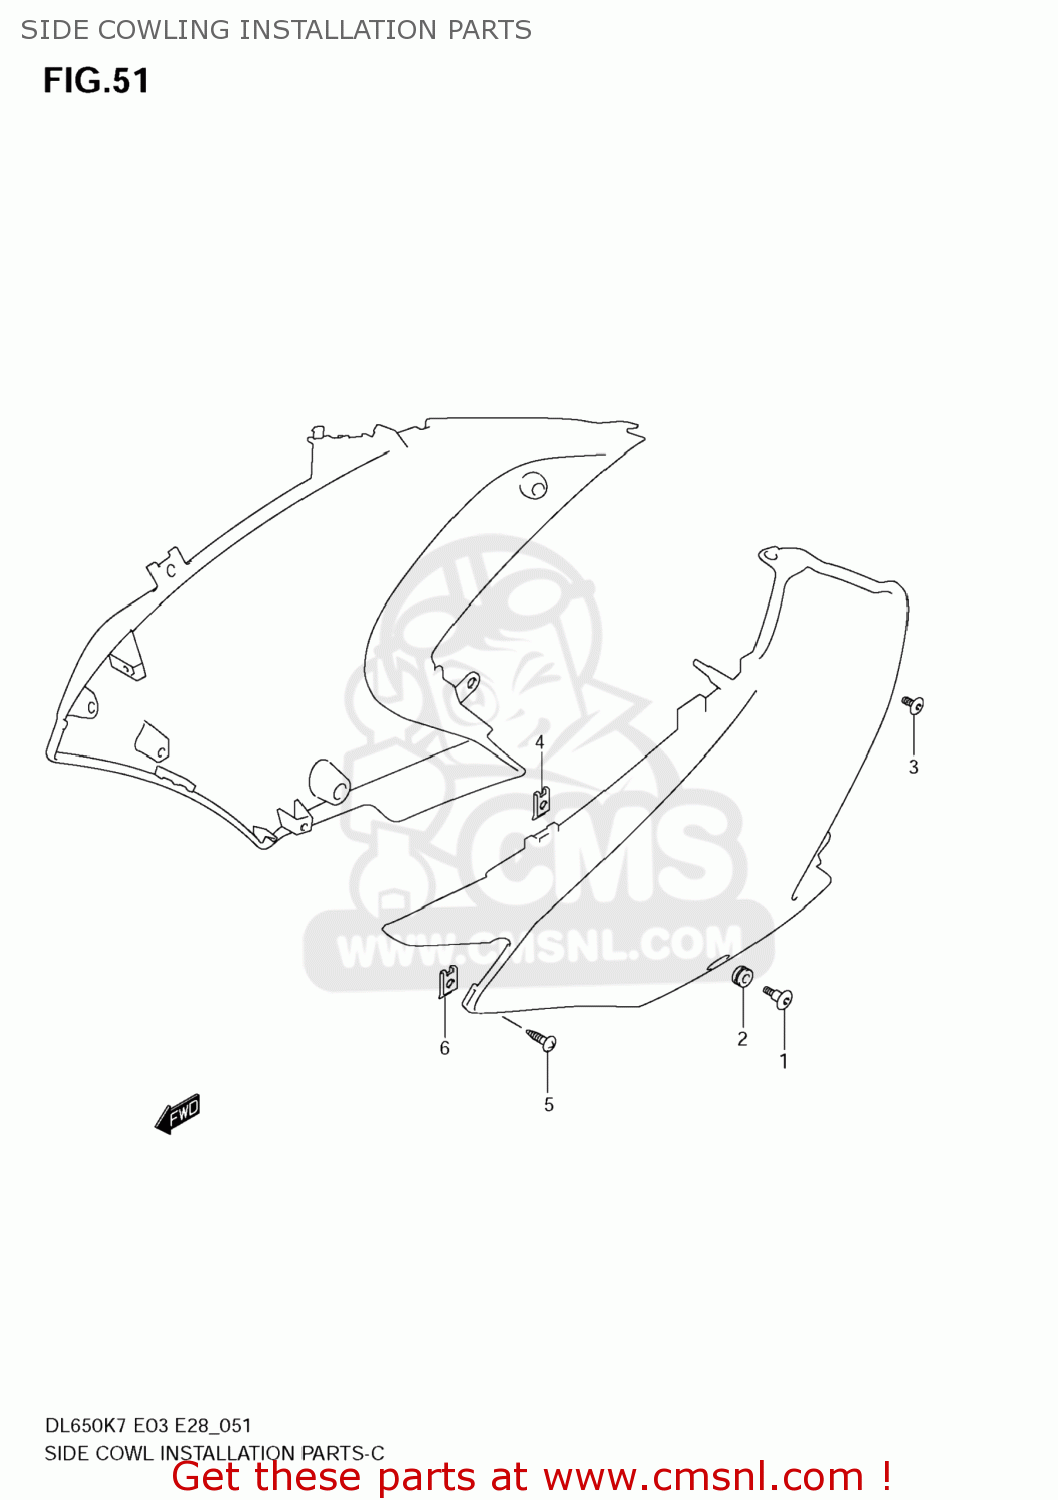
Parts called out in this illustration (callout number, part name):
1	SCREW(6X20)
2	CUSHION
3	SCREW(6X10)
4	NUT,COWL
5	SCREW
6	NUT
